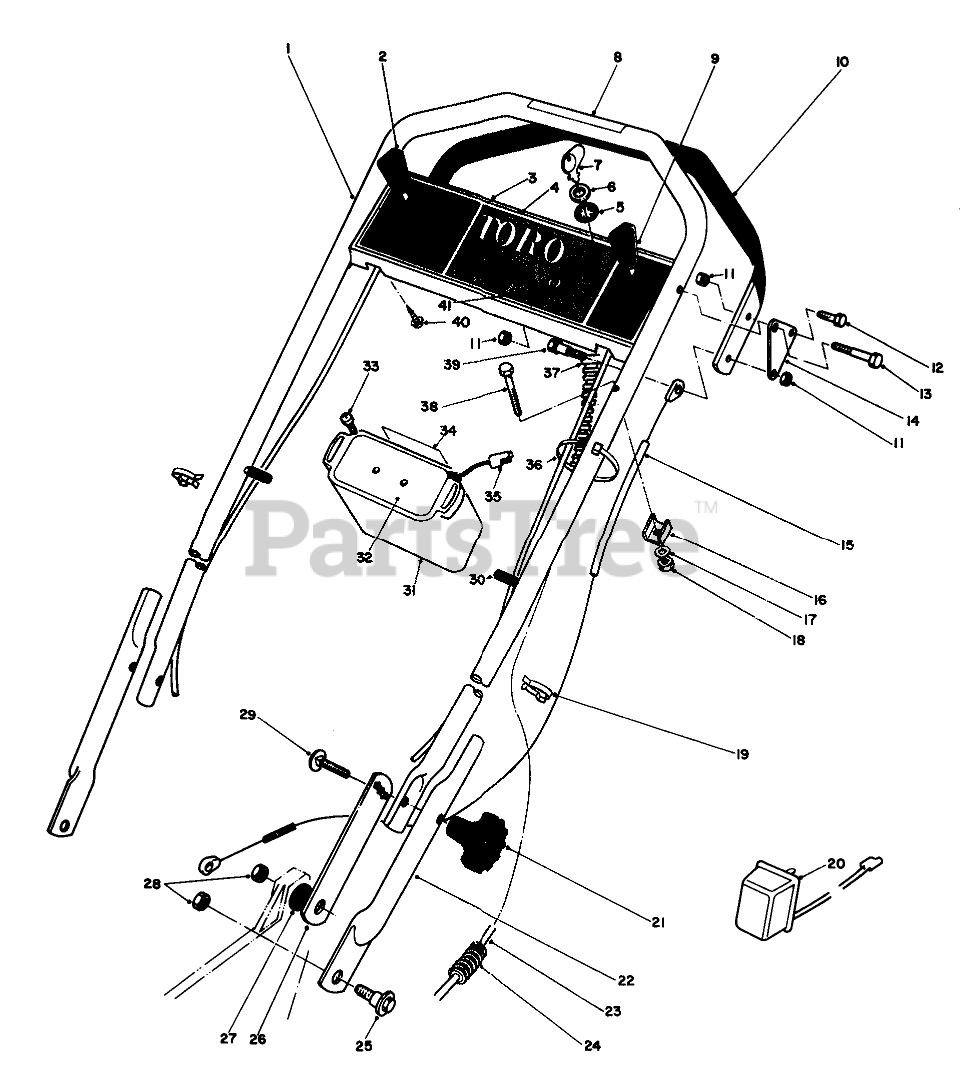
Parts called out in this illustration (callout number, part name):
1	Upper Handle
2	GROUND SPEED CONTROL
3	Control Panel (Incl. Ref. #4)
4	Decal-Control Panel
5	WASHER-TOOTH, INTERNAL
6	NUT-HH
7	Key
8	Decal-Select-a-Pace
9	Throttle Control
10	DEMAND HANDLE ASM
11	NUT-LOCK, CONE
12	SCREW-HH
13	BOLT-SHOULDER
14	Bracket Demand
15	DEMAND HAND CABLE
16	CLAMP-CABLE
17	WASHER-FLAT
18	NUT-LOCK, NI
19	BOWDEN CLIP
20	Charger
22	LOWER HANDLE
23	WIRE HARNESS
24	Cover-Wiring Harness
25	SCREW-SHOULDER
26	HANDLE LATCH
27	HANDLE LATCH SPACER
28	Nut
29	SCREW-CARR
30	CAP-VINYL
31	Battery Case
32	BATTERY COVER
34	Decal
35	Plug & Wire
36	TIE-CABLE
37	RING FITTING
38	SCREW-HH
39	SHOULDER BOLT
40	SCREW-HWHTF
41	Starter Switch (Incl. Ref. #5-7)
